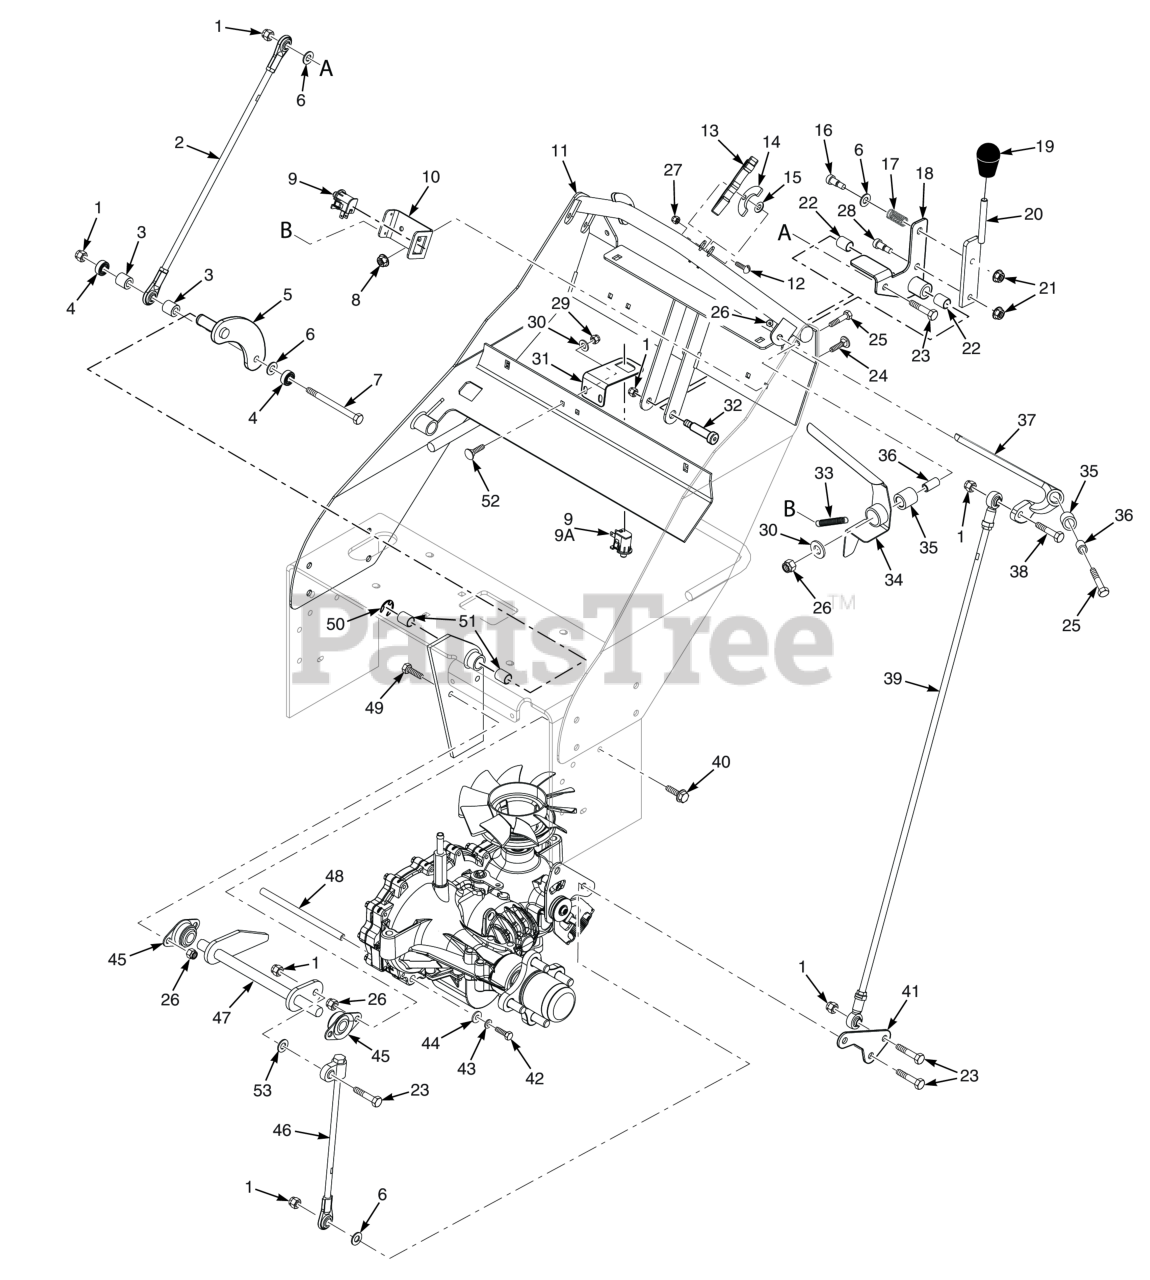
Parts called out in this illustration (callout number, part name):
1	HEX NUT, ELASTIC STOP LOCK, 3/8-16
2	Linkage, Speed Control
3	Spacer, Idler Pulley - SFZ52
4	Bearing
5	Neutral Plate Weldment
6	Flatwasher, 3/8 (.406 x .812 x .065)
7	Bolt, Hex Head, 3/8-16 x 3-1/2"
8	NUT, 1/4-20 SERRATED FLANGE HEX HEAD
9	SWITCH, NEUTRAL INTERLOCK
9A	Switch, Double Pole - Plunger
10	Bracket, Operator Presence Switch
11	Handle Assy, W/Decals
12	Machine Screw, #10-32 x 1-1/4", Pan Head
13	Latch, Thumb
14	Plate, Anti-Friction
15	Washer, 1/4" Curved Spring
16	Bolt, Shoulder 3/8 x 1"
17	Spring, Speed Control Slide
18	Neutral Handle Assy
19	Knob, Soft Touch
20	Handle Weldment, Speed Control
21	Nut, Serrated Flange 5/16-18 (Right Front Engine Mounting, Briggs and Kohler Only)
22	Bearing, Plastic 1/2" I.D.
23	Bolt, Hex Head 3/8-16 x 1-1/2" B&S 32BV
24	Bolt, Carriage, 1/4-20 x 1-1/4"
25	Bolt, Hex Head 5/16-18 x 1-1/2" - Front
26	HEX NUT, ELASTIC STOP LOCK, 5/16-18
27	HEX NUT, ELASTIC STOP LOCK # 10-32
28	Bolt, Shoulder 3/8 x .375"
29	HEX, NUT, ELASTIC STOP LOCK, 1/4-20
30	Flatwasher, 5/16-.375 x .875 x .083 (35BV & 37BV-EFI)
31	Bracket, Neutral Switch (Manual Start)
32	Bolt, Shoulder 1/2 x 2"
33	Spring, Operator Presence
34	Handle, Op. Presence-LH
35	Bearing
36	Sleeve, Handle Pivot
37	Handle Assembly-LH
38	Bolt, Hex Head 3/8-16 x 1-3/4" (Kohler EFI)
39	Linkage, Steering
40	Capscrew, 5/16-18 x .75 Serrated Flange Hex Head
41	Bracket, Transaxle Control
42	Capscrew, Hex Head 3/8-16 x 2.0"
43	Lockwasher, 3/8" Spring, Kawasaki FX / FT & FT-EFI / B&S 32BV
44	Flatwasher, 3/8" Special (.391 x .938 x .105)
45	Bearing, Self Aligning - 5/8 I.D.
46	Linkage, Pump
47	Weldment, Bellcrank-LH
48	Spacer, Axles
49	Bolt, Heax Head 5/16-18 x 1" (48V / 52V)
50	RETAINING RING, 5/8" EXTERNAL "E"
51	Bearing
52	Serr. Fl. Hex Head CPSCR, 1/4-20 x 3/4"
53	Flatwasher, 3/8 (.391 x .938 x .105 HD) Grade 8
